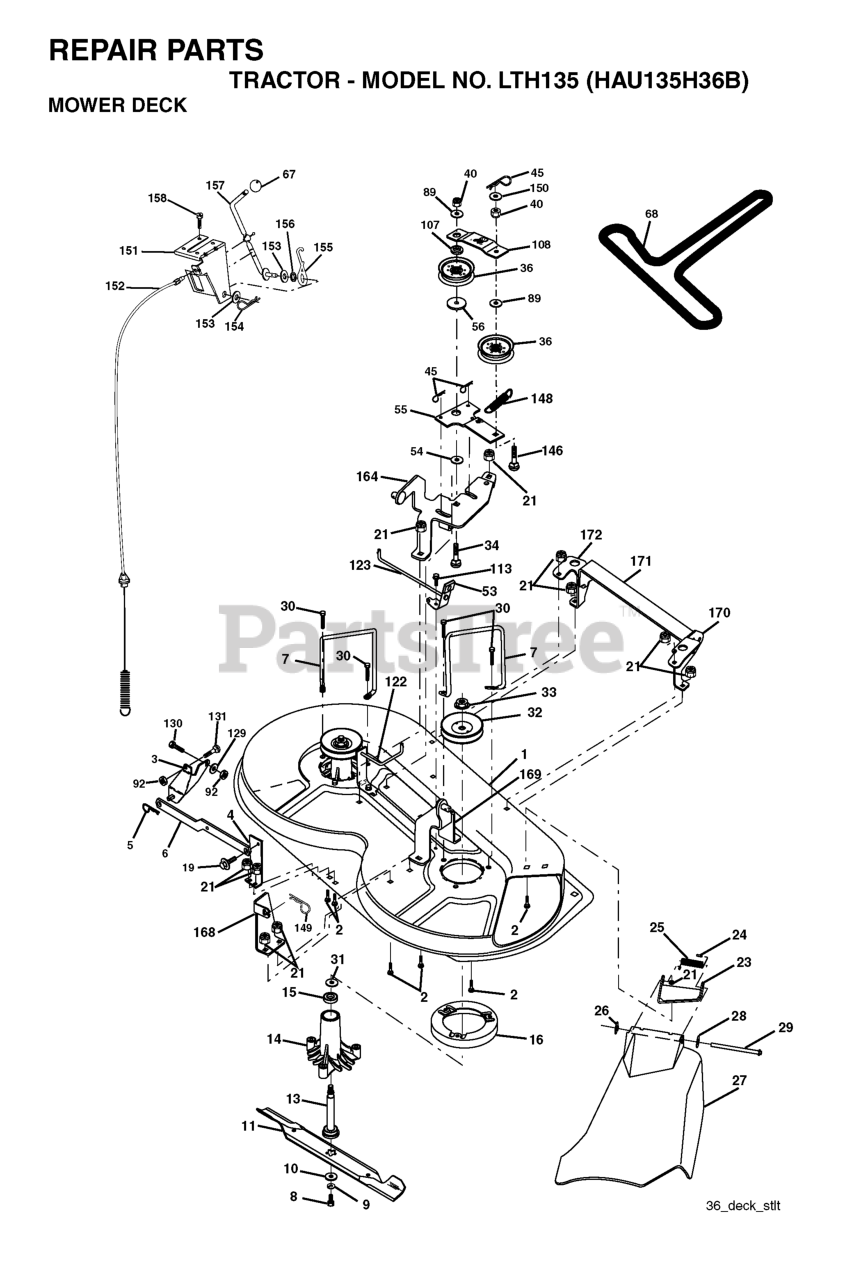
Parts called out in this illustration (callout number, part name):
2	RP BOLT 5/16-18 X3/4 ZN/YEL GR
3	BRKT ASM SWAY BAR
5	RETAINER-SPRNG RB
6	BAR SWAY DECK
8	BLADE BOLT
9	LOCKWASHER
10	WASHER.BLADE
11	BLADE, HI-LIFT 36" PREMIUM
13	SHAFT ASM VENT
14	HOUSING.MANDREL.VENTED (MACHD)
16	STRIPPER.MANDREL.ROUND.BLACK
19	BOLT SHD 5/16-18
21	LOCKNUT
23	BRACKET ASM DEFLECTOR
24	CAP-SLEEVE LT
25	SPRING TORSION
26	NUT PUSH M
27	CONSOLE.STLT.5SP.BLK
28	Washer 11/32 x 5/8 x 16 Ga SD
29	HINGE ROD
30	SCREW, WASHER HEAD
31	WASHER
32	PULLEY, MANDREL
33	NUT, FLG TOPLOCK 9/16"
36	FLAT IDLER PULLEY
45	RETAINER M
53	BRAKE ASSEMBLY
56	SPACER.RETAINER.MOWER
67	KNOB T (3/8 HOLE)
89	WASHER GT
92	NUT
107	SPACER.IDLER.ARM
108	STIFFENER.IDLER.ARM
113	Screw 5/16-18 x 1/2 Hex, Self Tapping 5/16-18 x 1/2
129	WASHER
131	BOLT D
146	BOLT, CARRIAGE IDLER
148	IDLER RETURN SPRING
149	SPRING.RETAINER.YELLOW.ZINC
151	BRACKET.CLUTCH.CABLE
153	WASHER FLAT 3/8"
154	SPRING RETAINER
155	SPRING RETENTION LEVER
156	SPACER.CLUTCH.CABLE
157	ROD CLUTCH CABLE 3/8"
158	SCREW
171	BRACE.SUPT.SUSP.FRT.CRD
